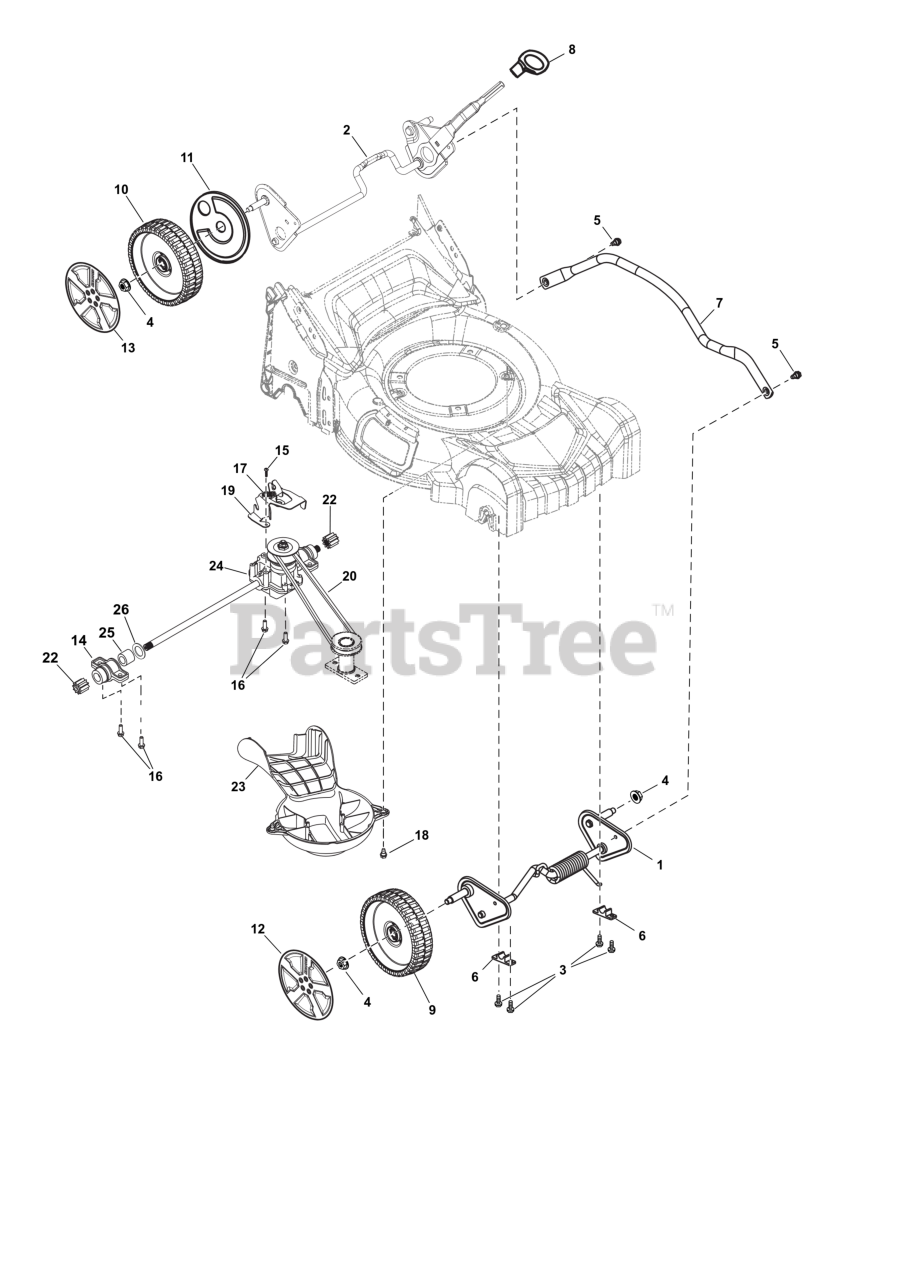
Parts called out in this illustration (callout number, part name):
1	AXLE, Front
2	AXLE, Rear
3	HWST, 1/4-15X3/4 BZ
4	NUT, 3/8-16 HEX NYLOCK
5	SCREW, 1/4-20 x 1/2
6	BUSHING, Lock
8	KNOB, Black
9	WHEEL, 200 x 49
10	WHEEL, Drive
11	DUST COVER, Wheel
12	HUBCAP, Front
13	HUBCAP, Rear
14	BEARING ASSEMBLY
15	SCREW, Hex Washer Head, .159 x .43
16	SCREW, 1/4-15 x 1-1/4
18	SCREW, 1/4-20 x 1/2
19	BRACKET
22	GEAR, 9 Tooth
23	COVER, Rear
24	TRANSMISSION
